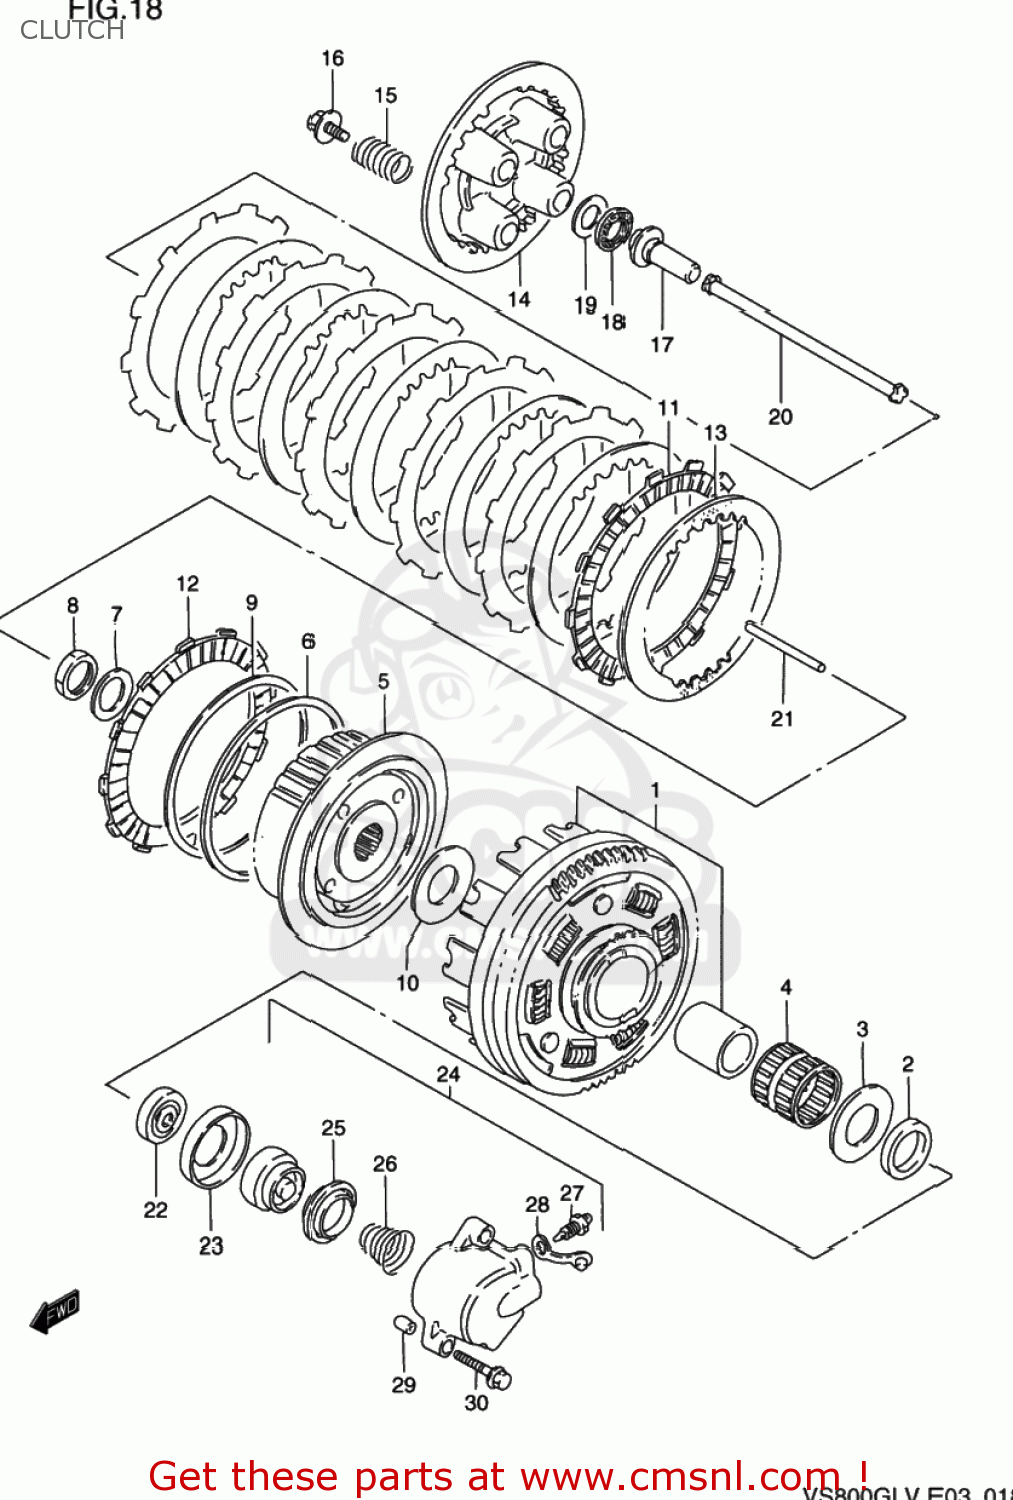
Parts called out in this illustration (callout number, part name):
1	GEAR ASSY,PRIMARY(NT:71)
2	SPACER(25X38X6.5)
3	WASHER(25X50X2.5)
4	BEARING(35X40X35.8)
5	HUB COMP,CLUTCH SLEEVE
6	SEAT,WAVE WASHER(T:1.4)
7	WASHER
8	NUT
9	WASHER
10	WASHER(25X50X2.5)
11	PLATE,CLUTCH DRIVE (NAS)
12	PLATE,CLUTCH DRIVE(T:3.5) (NAS)
13	PLATE,CLUTCH DRIVEN(T:1.6) (NAS)
14	DISC,CLUTCH PRESSURE
15	SPRING
16	BOLT
17	PIECE,CLUTCH PUSH
18	BEARING(15X28X2)
19	WASHER
20	ROD,CLUTCH
21	ROD,CLUTCH PUSH,L
22	SEAL,OIL(6X34X11)
23	RETAINER,CL PUSH ROD OIL SEAL
24	CYLINDER,CLUTCH RELEASE
25	CUP,CLUTCH CYLINDER
26	SPRING,CLUTCH CYLINDER
27	BLEEDER
28	CAP,BLEEDER
29	PIN
30	BOLT
